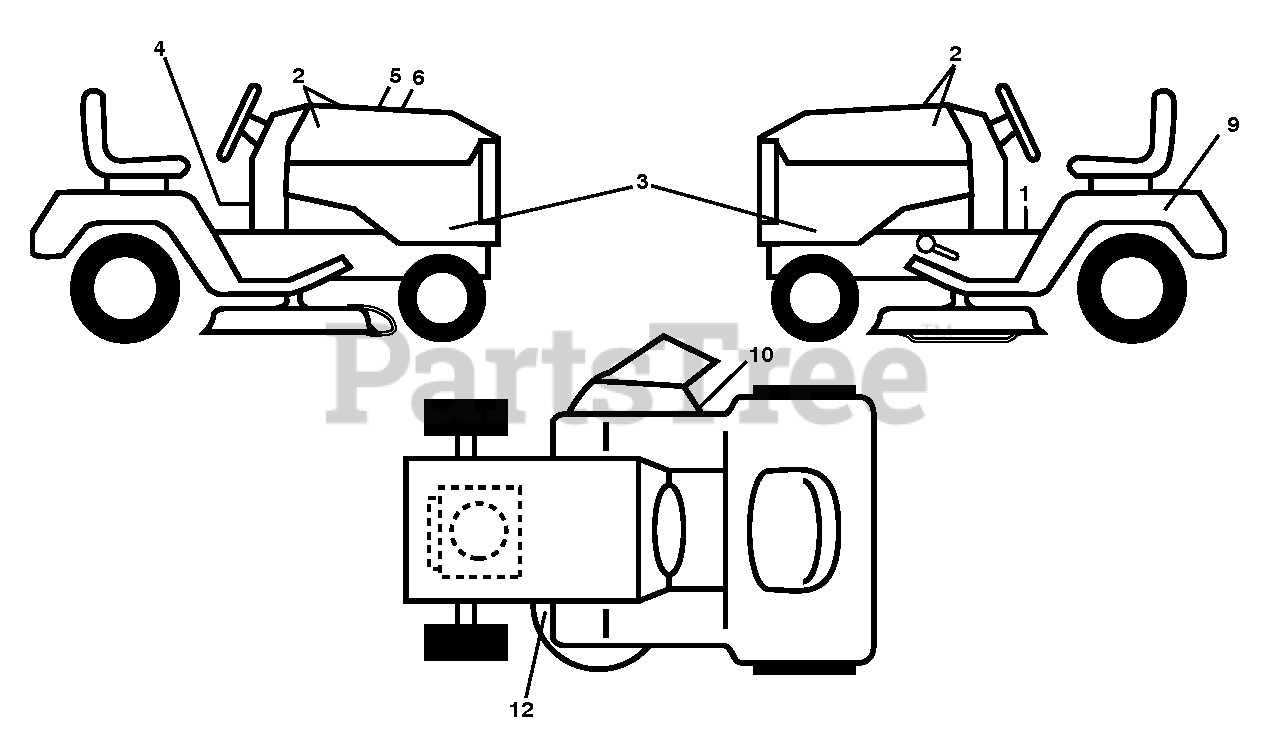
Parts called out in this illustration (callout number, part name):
1	DECAL.FENDER.WARNING
2	RP.DECAL.BADGE.170MM.TEXTLOGO
3	Decal, Side Panel YTH20K46 Set
4	LABEL.EPA.COMPLIANCE
5	DECAL.WARNING.CUST.RESP.E85.
9	DECAL BTRY SYMBOLS
10	DECAL.WARN.KEEP.HAND.AWAY
12	DECAL V BELT SCHEMATIC
